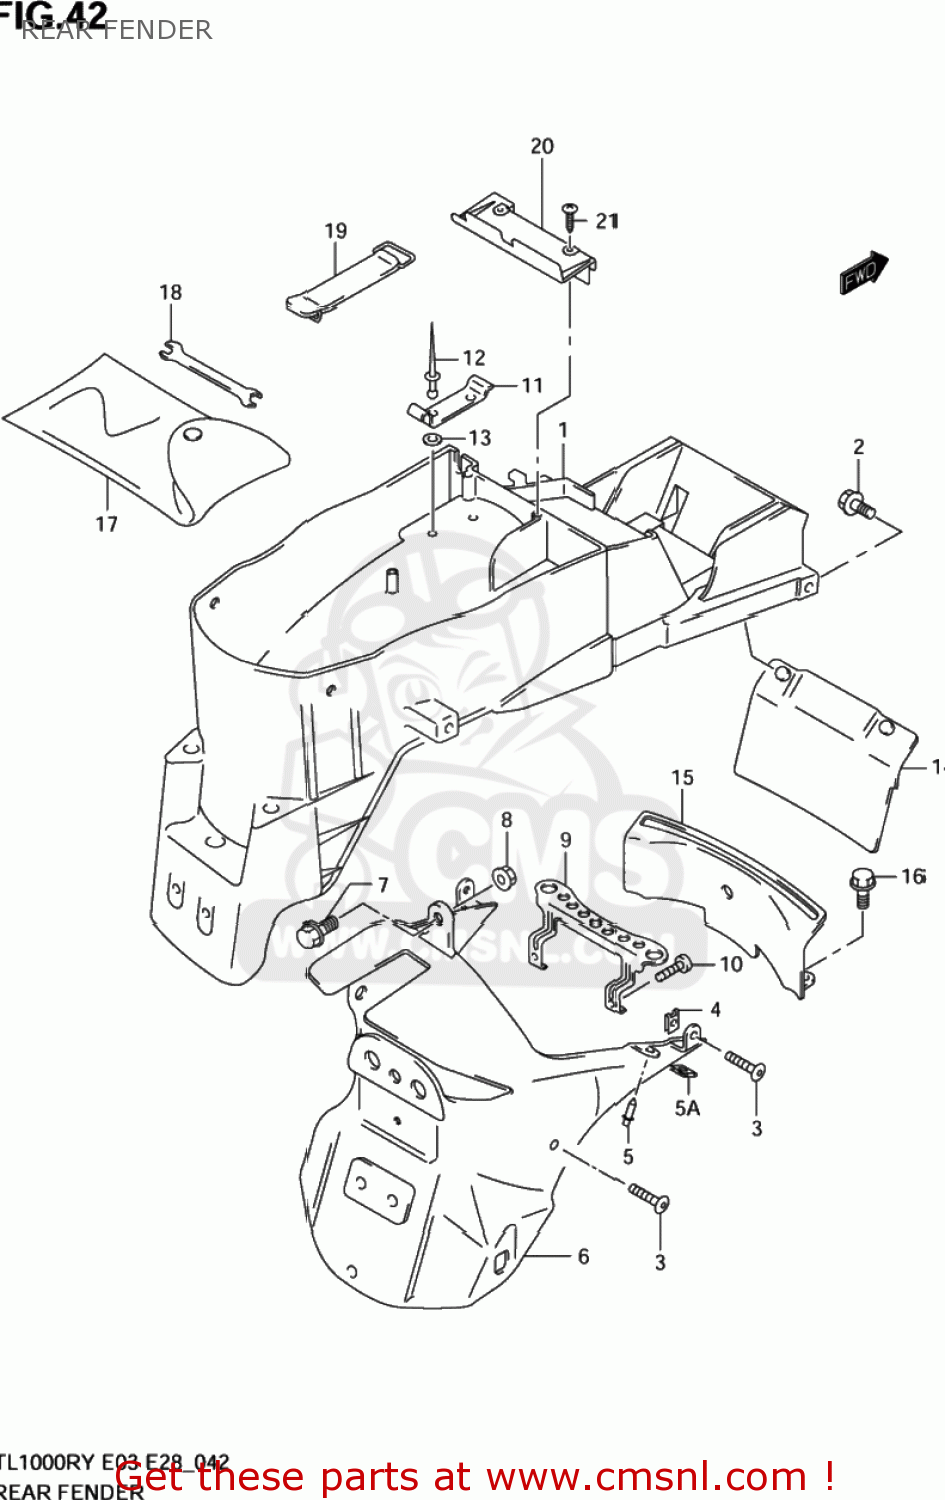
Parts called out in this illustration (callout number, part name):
1	FENDER,RR FR
2	BOLT 6X16
3	SCREW(5X12)
4	NUT
5	CLIP
5A	NUT
6	FENDER,RR RR
7	BOLT(6X16)
8	NUT
9	BRACKET,REAR COMBINATION LAMP
10	SCREW(5X16)
11	HOLDER,TOOL
12	RIVET
13	WASHER
14	MUD GUARD,REAR FENDER
15	MUDGUARD,RR FENDER FR LWR
16	BOLT(6X16)
17	TOOL ASSY
18	OPEN SPANNER(8X10)
19	BAND,TOOL
20	COVER,RR FENDER
21	SCREW
